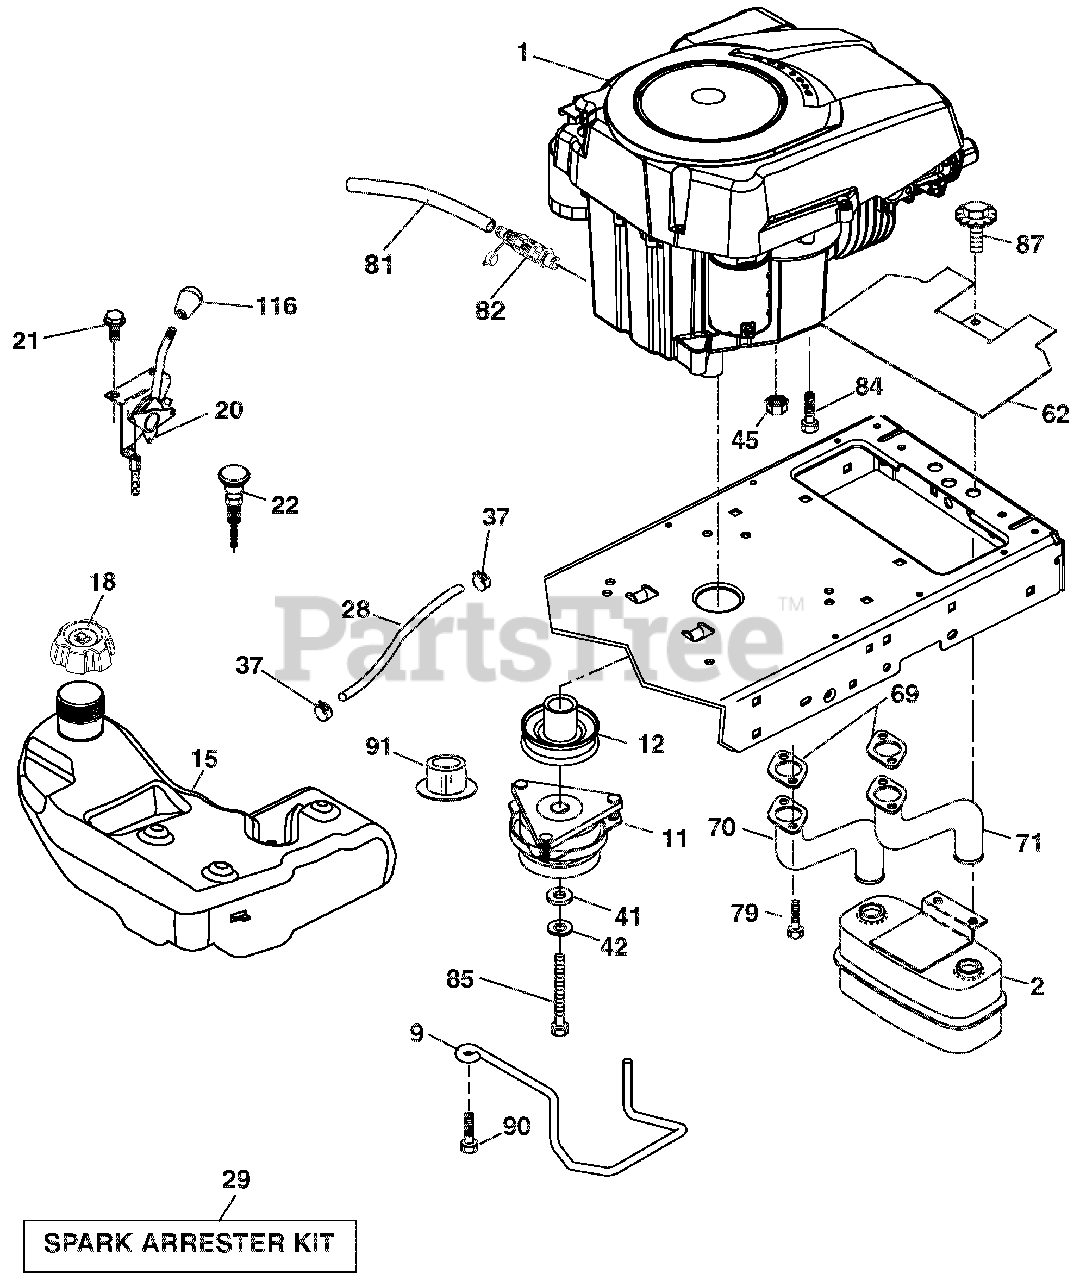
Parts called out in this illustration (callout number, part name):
1	ENGINE KOHL MODEL NO. SV730-3041(438325)(ORDER PARTS FROM ENGINE MANUFACTURER.)
2	MUFFLER ASM.TWIN.LO-TONE
9	KEEPER.BELT.ENGINE.3.25"NSTL
11	CLUTCH.ELECTRIC
12	PULLEY ENGINE
15	TANK.FUEL
18	CAP FUEL
20	CONTROL.THROTTLE
22	CONTROL CHOKE
28	LINE.FUEL.64"REAR.EMIS.CA.LP
29	KIT.SPARK ARRESTOR(392390 B&S)
37	CLAMP.HOSE.BLK.
41	WASHER.1-1/2 ODX15/32 IDX.250
42	WASHER.LOCK.HVY HLCL.SPR.7/16
45	Nut, Keps Hex 1/4-20 unc
62	SHIELD.HEAT.MUFFLER.
69	GASKET
70	PIPE.EXHAUST.LH.CV18/20
71	PIPE.EXHAUST.RH.CV18/20
79	SCREW.SOCKET HD.5/16-18 X .75
81	TUBE.DRAIN.OIL.EASY
82	VALVE OIL DRAIN
84	SCREW.3/8-16 X 1.SMGML.TAP/R
85	BOLT.HEX.7/16-20 X 3.75 X GR.
87	BOLT.5/16-18 UNC X 1 W/SEMS.BL
90	SCREW.3/8-16X1.SMGML.TAP/R.BLK
91	BUSHING.1.375OD.HEYCO 2210
116	KNOB SOFT TOUCH
